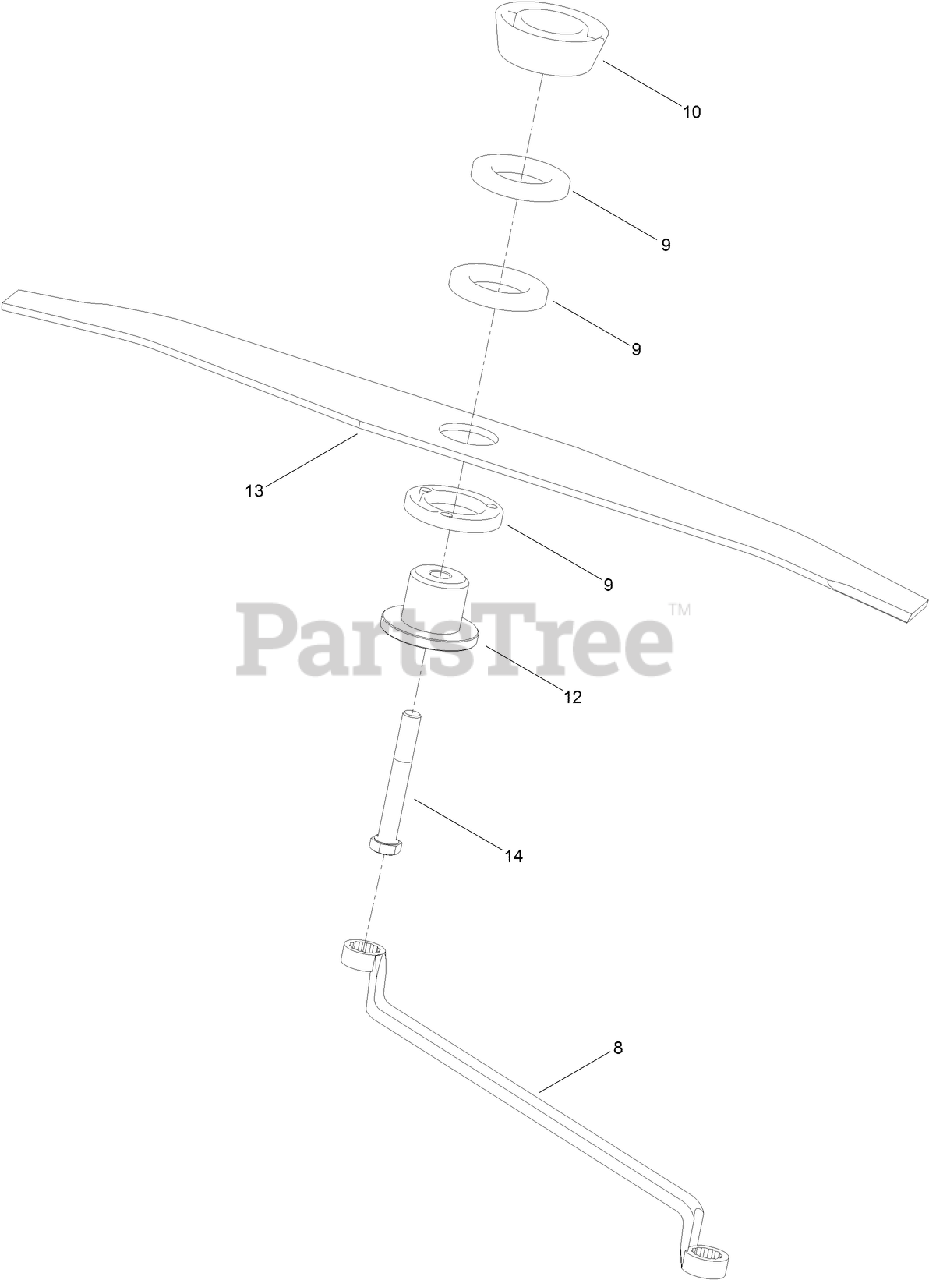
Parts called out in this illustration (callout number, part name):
8	SPANNER
9	SPACER-BLADE, ALUMINIUM
10	SPACER-DISTANCE
12	RETAINER-BLADE
13	BLADE
14	SCREW-SET
